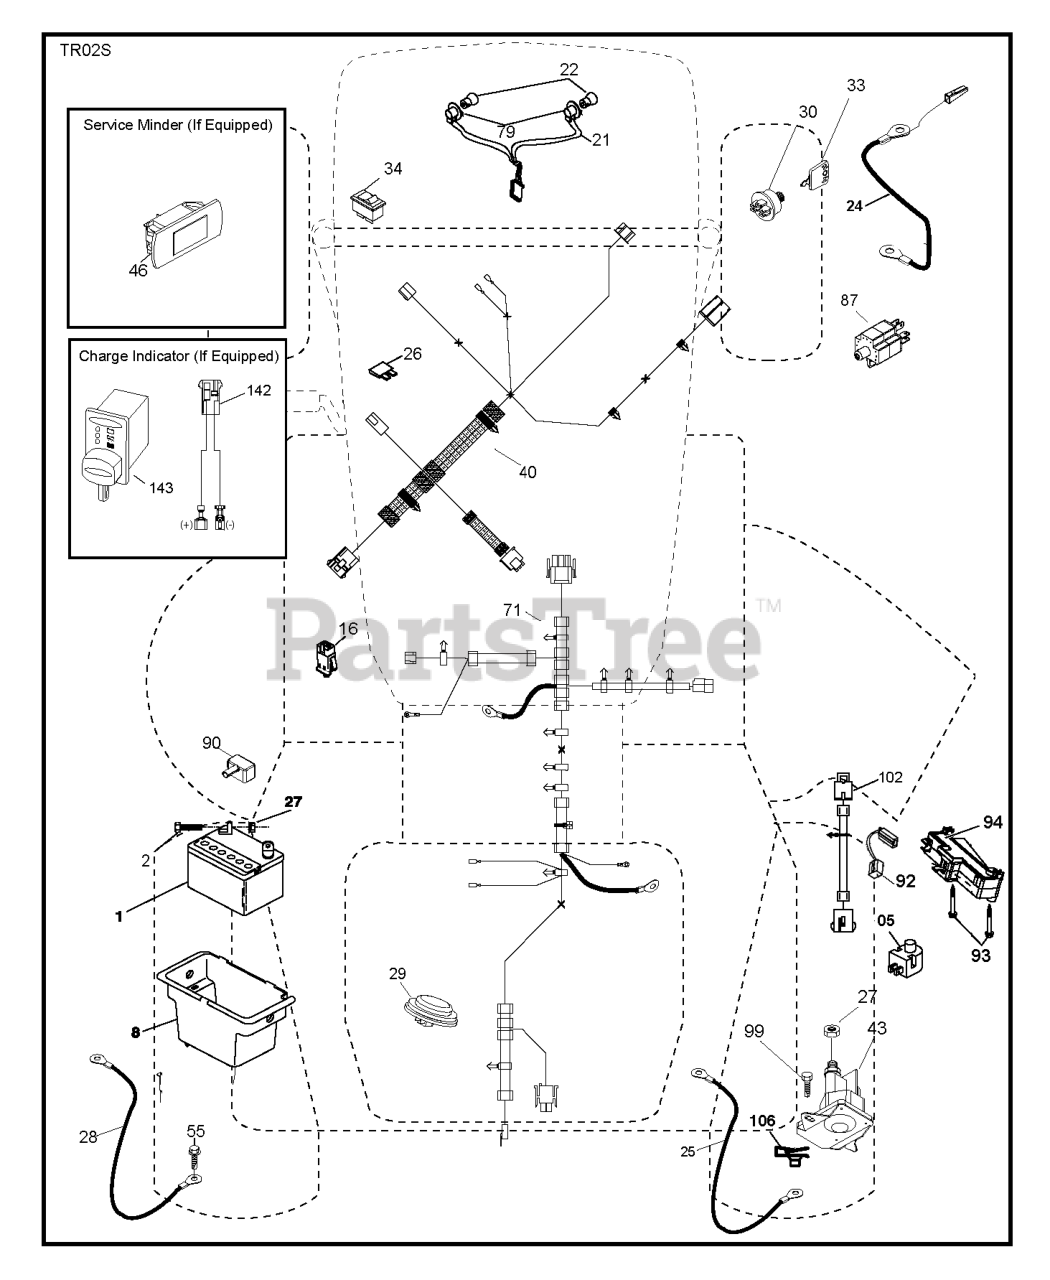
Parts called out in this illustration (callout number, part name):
1	Battery 12 Volt 25 Amp
2	BOLT.HEX.1/4.X.3/4.DICHROMATE
8	TRAY.ASM.BATTERY.FRT.TEX.CARB
8	BOX.BATTERY.MNT.REAR.L
16	SWITCH INTERLOOK PUSH-IN
21	HARNESS.LIGHT W/4152J BULBS
24	CABLE.FRBATT.W/WIRE.8GA.8
25	CABLE.BATT.RED.8GA.17
25	CABLE.STARTER.8GA.17.5
26	FUSE 20AMP
28	CABLE.GROUND.21"BLK.8GA.90T
28	CABLE.GROUND.REAR.BATTERY.8G
29	SWITCH.SEAT.DELTA.OPC.
30	SWITCH.IGN.DELTA.W.LGH.ROS
33	KEY.CHAIN.BLISTER.PACK.GEN.INT
40	HARNESS.IGN.DASH.CBL.YTGT.PRED
40	HARNESS.TEX.DASH.MAN.REAR BATT
46	GUAGE.SRVCMNDR.HRMTR.
55	SCREW 5/16"
71	HARNESS.CHASSIS.RRBATT.RDYSTRT
71	HARNESS-CHASSIS SUB
79	BULB HOLDER ASM.
87	SWITCH.INTRLCK.CLUTCH.
90	COVER.TERMINAL.BATTERY
92	HARNESS.PIGTAIL.CONSLE
93	Bolts
94	MODULE.REVERSE.ROS
99	SCREW HEXWSHR 1/4-20X3/4
102	HARNESS PIGTAIL PCH TEX ROS
105	REVERSE SWITCH
106	1/4-20 U NUT
